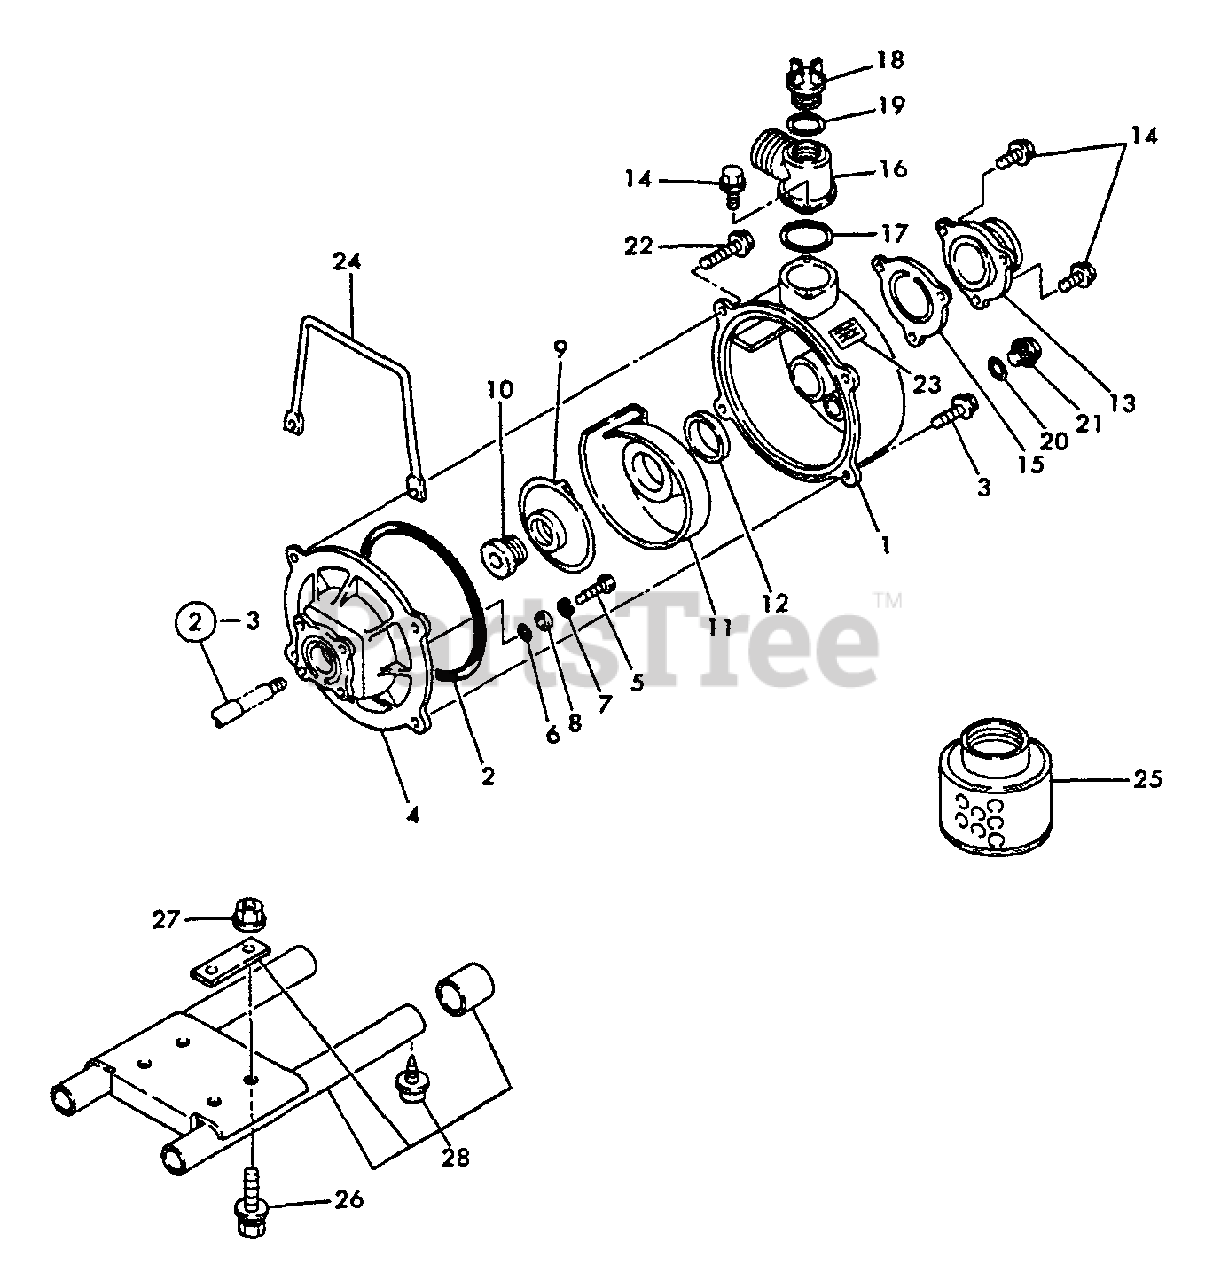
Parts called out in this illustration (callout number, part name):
1	CASING
2	GASKET, CASING
3	BOLT - 8X25
4	COVER, PUMP CASE
5	BOLT - 8X48
7	LOCKWASHER
8	WASHER - 8
9	IMPELLER, SHIM 0.3 Y40106000000
10	SEAL
11	CASING, INNER
12	GASKET, INNER CASING
13	CASE
14	BOLT - 6X20
15	VALVE, CHECK
17	GASKET, BEND
19	GASKET, PLUG
20	GASKET, DRAIN BOLT
21	BOLT, DRAIN - 12X20
22	BOLT - 8X40
23	LABEL - MODEL
24	HANDLE
25	STRAINER, DEBRIS
26	BOLT - 8X45
27	NUT - 8
